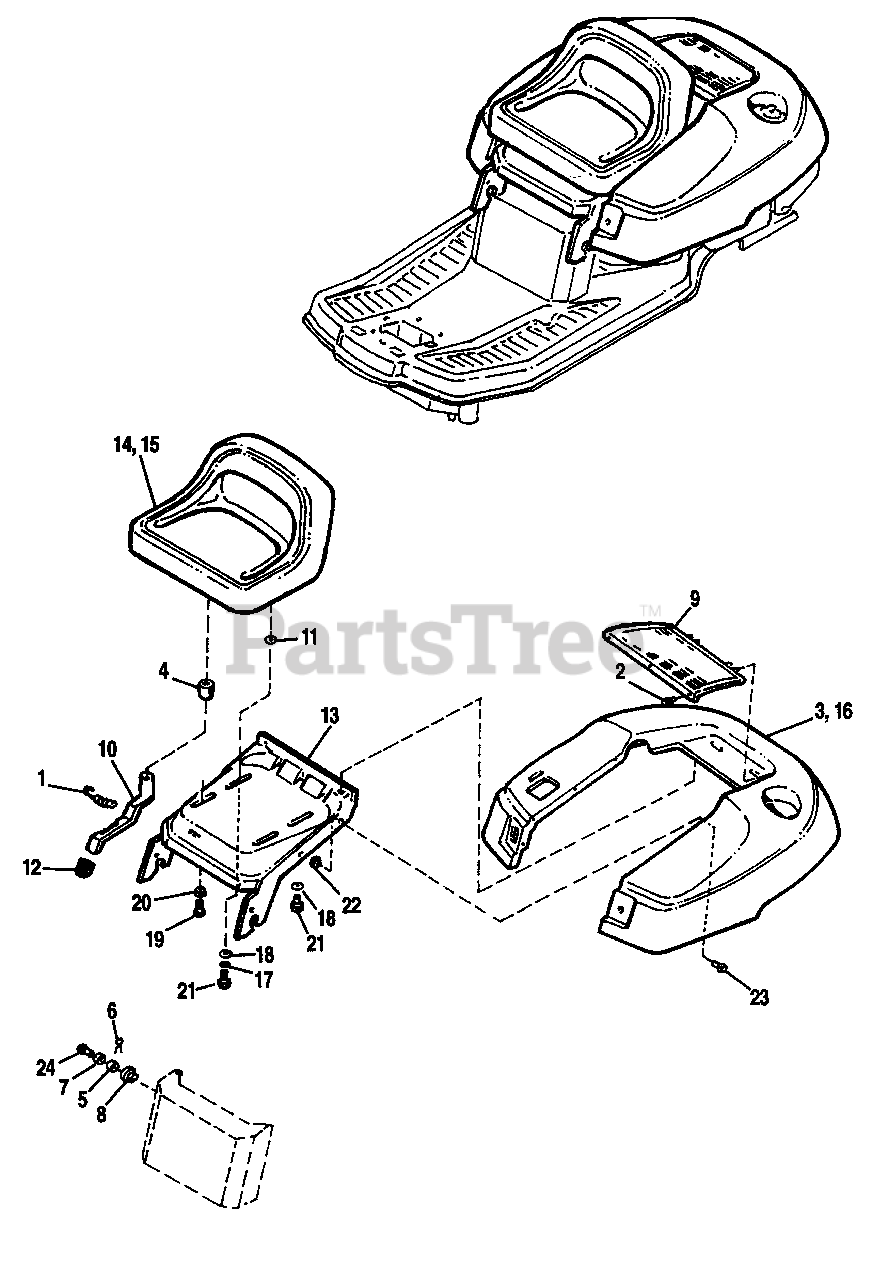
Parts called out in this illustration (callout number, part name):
3	DECK, Seat (Orange)
5	SPACER, Hood
6	CLIP, Hairpin
7	PIVOT, Hood
9	SCREEN
10	ADJUSTER, Seat
11	SPACER, Seat Side
12	CAP, Vinyl, Black
13	SUPPORT, Seat
14	SEAT ASSY. (Includes Ref. No. 15)
15	COVER, Seat
16	DECK, Seat (Red)
17	LOCKWASHER, 5/16
18	WASHER, Plain, 11/32 x 1 x 1/8
19	CAPSCREW, Hex Hd., 5/16-18 x 1-1/4
20	NUT, Hex, 5/16-18
21	CAPSCREW, Hex Hd., Whizlock, 5/16-18 x 3/4
22	NUT, Hex, Flange Lock, 1/4-20
23	CAPSCREW, Hex Hd., 1/4-20 x 5/8
24	SCREW, Taptite, 5/16-18 x 1
